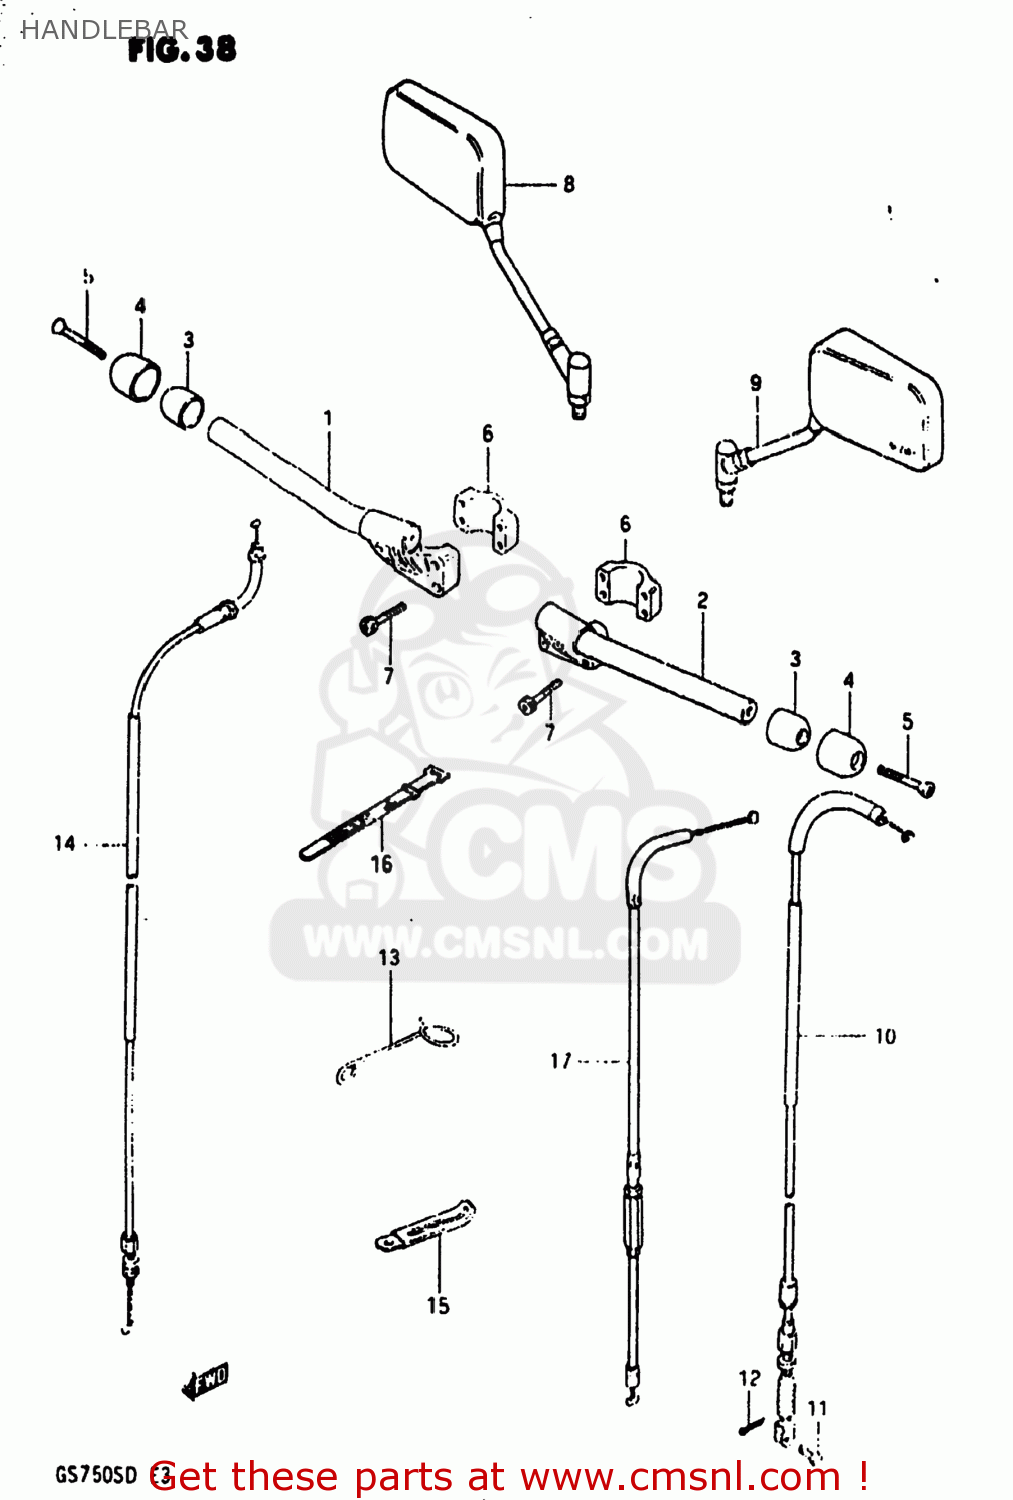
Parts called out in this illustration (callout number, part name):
1	HANDLEBAR,R
2	HANDLEBAR,L
3	BALANCER,HANDLEBAR
4	CAP,HANDLE BALANCER
5	SCREW 6X55
6	HOLDER,HANDLEBAR
7	BOLT
8	MIRROR ASSEMBLY,REAR VIEW
9	MIRROR ASSEMBLY,REAR VIEW
10	CABLE ASSY,CLUTCH
11	PIN(L:15)
12	PIN
13	GUIDE,CLUTCH CABLE
14	CABLE ASSEMBLY,THROTTLE
15	CLAMP
16	CLAMP(L:80)
17	CABLE,CLUTCH
